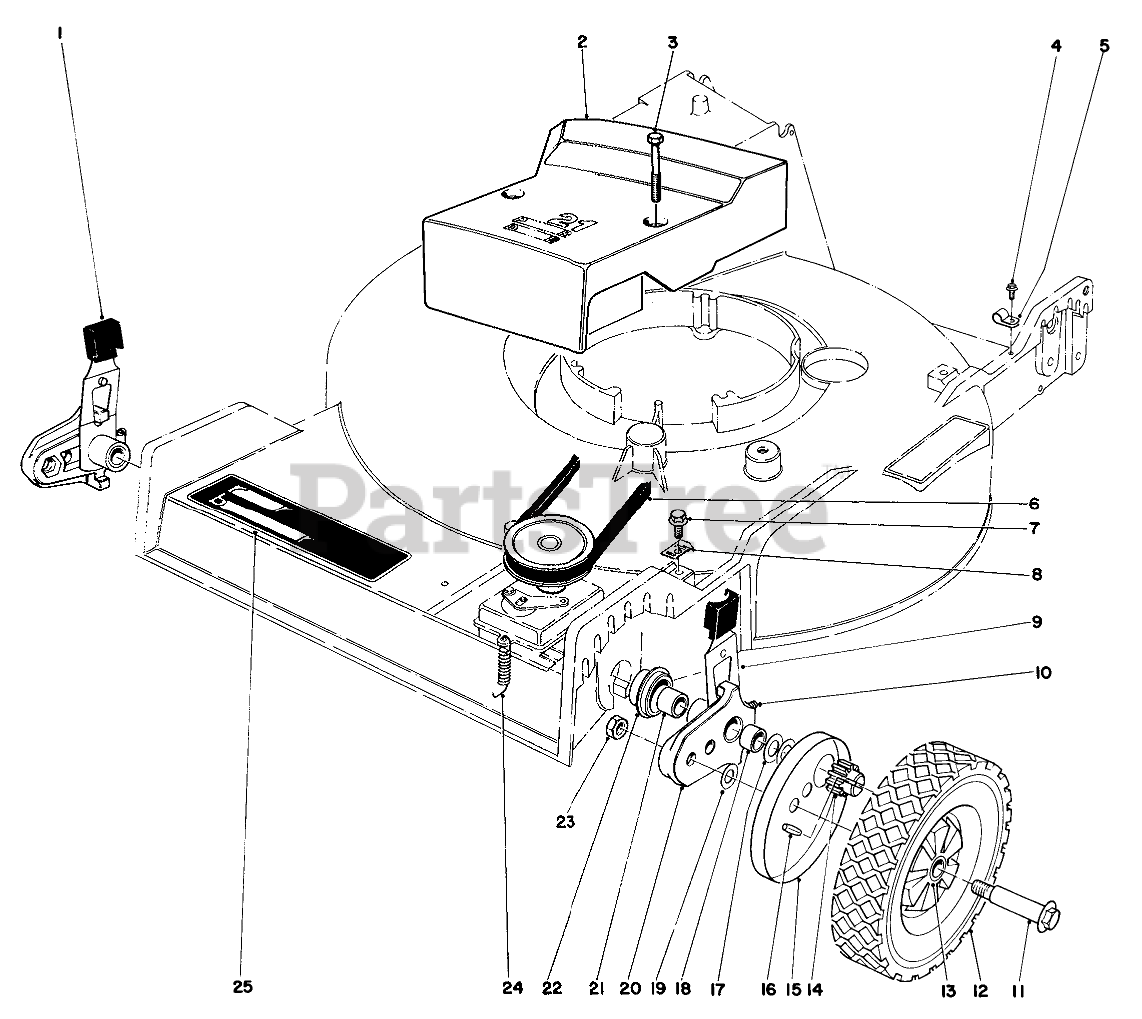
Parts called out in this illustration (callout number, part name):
1	KNOB-ARM
2	Cover-Belt
3	Screw-Thread Cutting
4	SCREW
5	CLAMP-CABLE
6	V BELT
7	SCREW-HWHTF
8	Cable Clamp
9	SPRING ARM ASM SP
10	FITTING-GREASE
11	BOLT-WHEEL
12	Wheel, Gear, & Tire Assembly (Incl. Ref. #12)
13	BUSHING
14	PINION GEAR 15T
15	Cover-Wheel
16	Pin
17	THRUST WASHER
18	BUSHING
19	WASHER
20	Pivot Arm Assembly (Incl. Ref. #10, 18, & 21)
21	BUSHING
22	END CAP
23	Nut
24	TENSION SPRING
25	Decal-Deck
